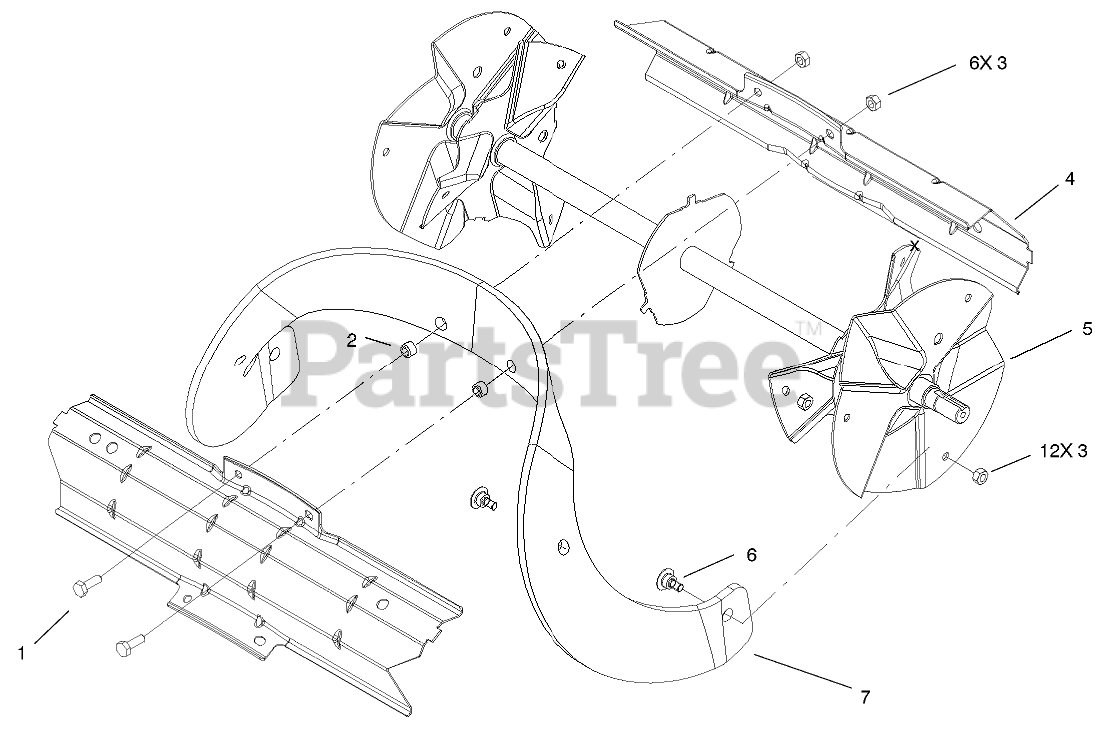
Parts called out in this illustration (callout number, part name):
1	SCREW-HH
2	SPACER-BLADE, ROTOR
3	NUT-LOCK, NI
4	DRUM-ROTOR
5	ROTOR ASM
6	SCREW
7	BLADE-ROTOR
